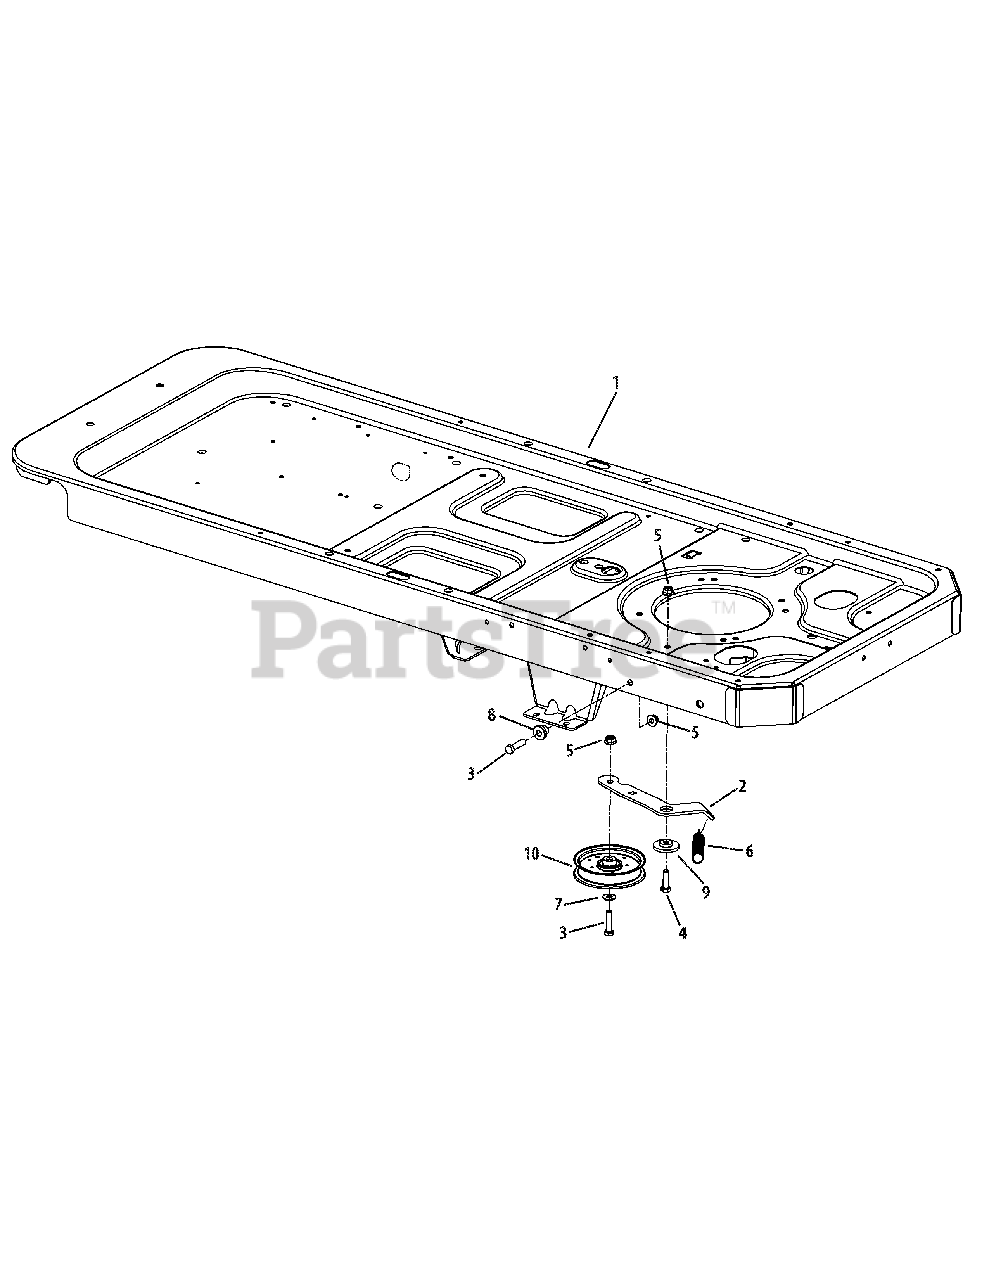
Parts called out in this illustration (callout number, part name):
1	Frame Assembly - Black Jack
1	Frame Assembly - Green
3	Hex Screw, 3/8-16 x 1.5
4	Hex Screw, 3/8-16 x 1.25
5	Flange Nut, 3/8-16
6	Extension Spring, .75 x 5.06
7	Flat Washer, .406 x .875 x .059
8	Shoulder Spacer, .39 x 1.0 x .7
9	Shoulder Spacer, .884 x .19
10	Idler Pulley, 4.25 Dia.
